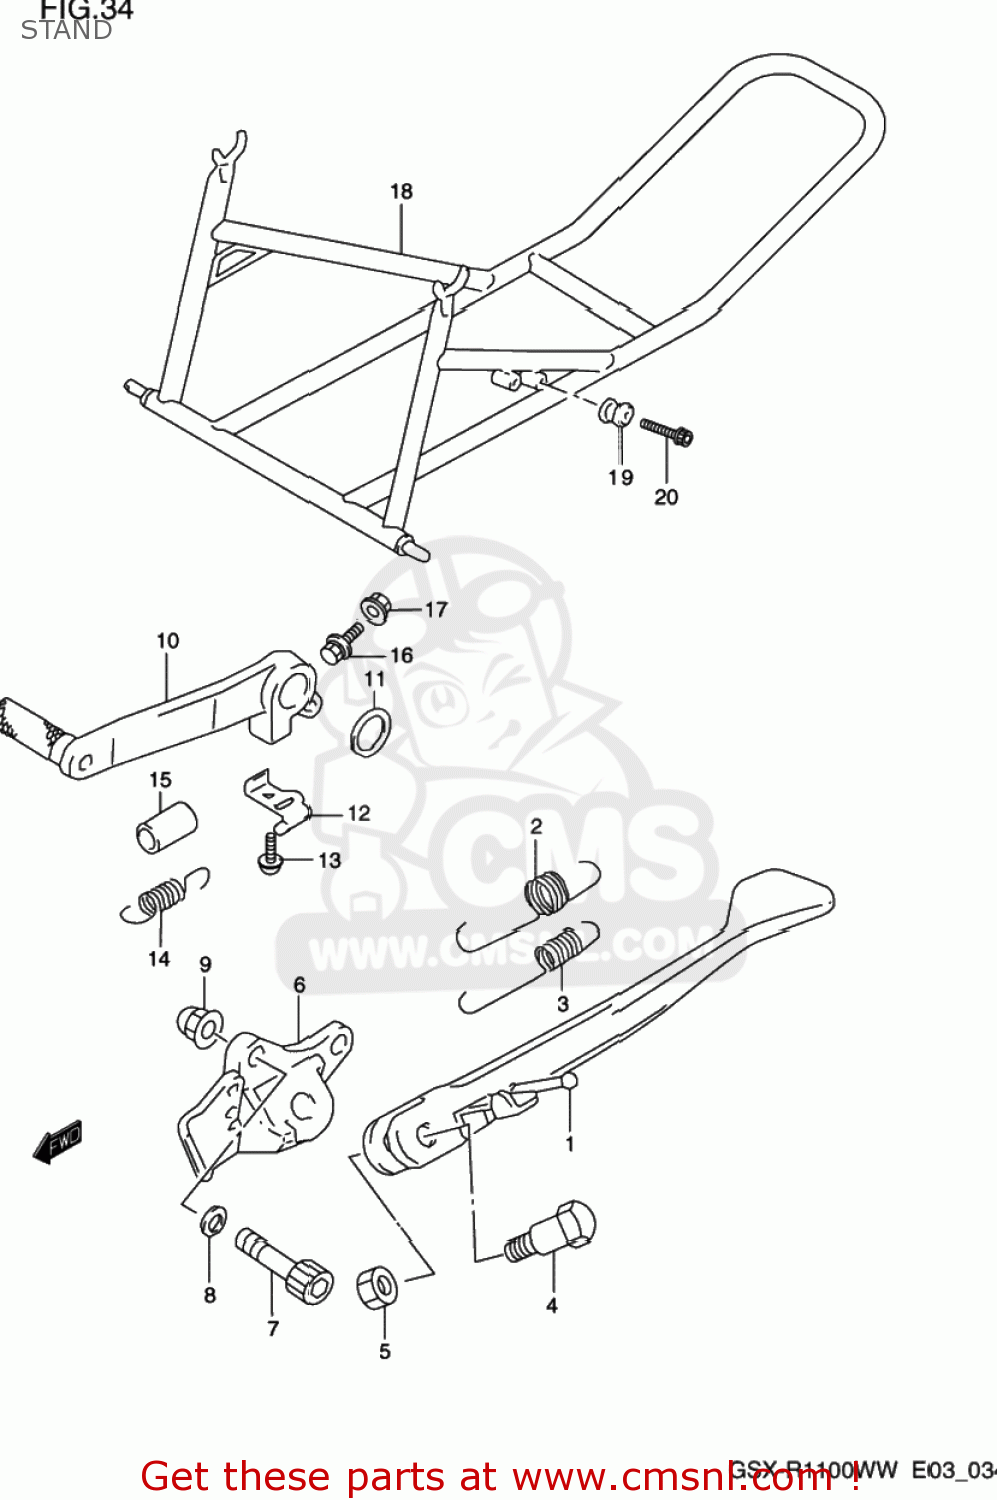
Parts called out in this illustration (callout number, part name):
1	STAND,PROP
2	SPRING
3	SPRING
4	BOLT(10X38)
5	NUT
6	BRACKET COMP,PROP STAND
7	BOLT 10X38
8	WASHER
9	NUT
10	PEDAL,BRAKE
11	WASHER(18X24X1)
12	HOOK,RETURN SPRING
13	SCREW(6X12)
14	SPRING
15	TUBE,BRAKE SPRING GUIDE
16	BOLT 5X20
17	NUT
18	STAND ASSEMBLY,REAR
19	HOLDER,STAND
20	BOLT
